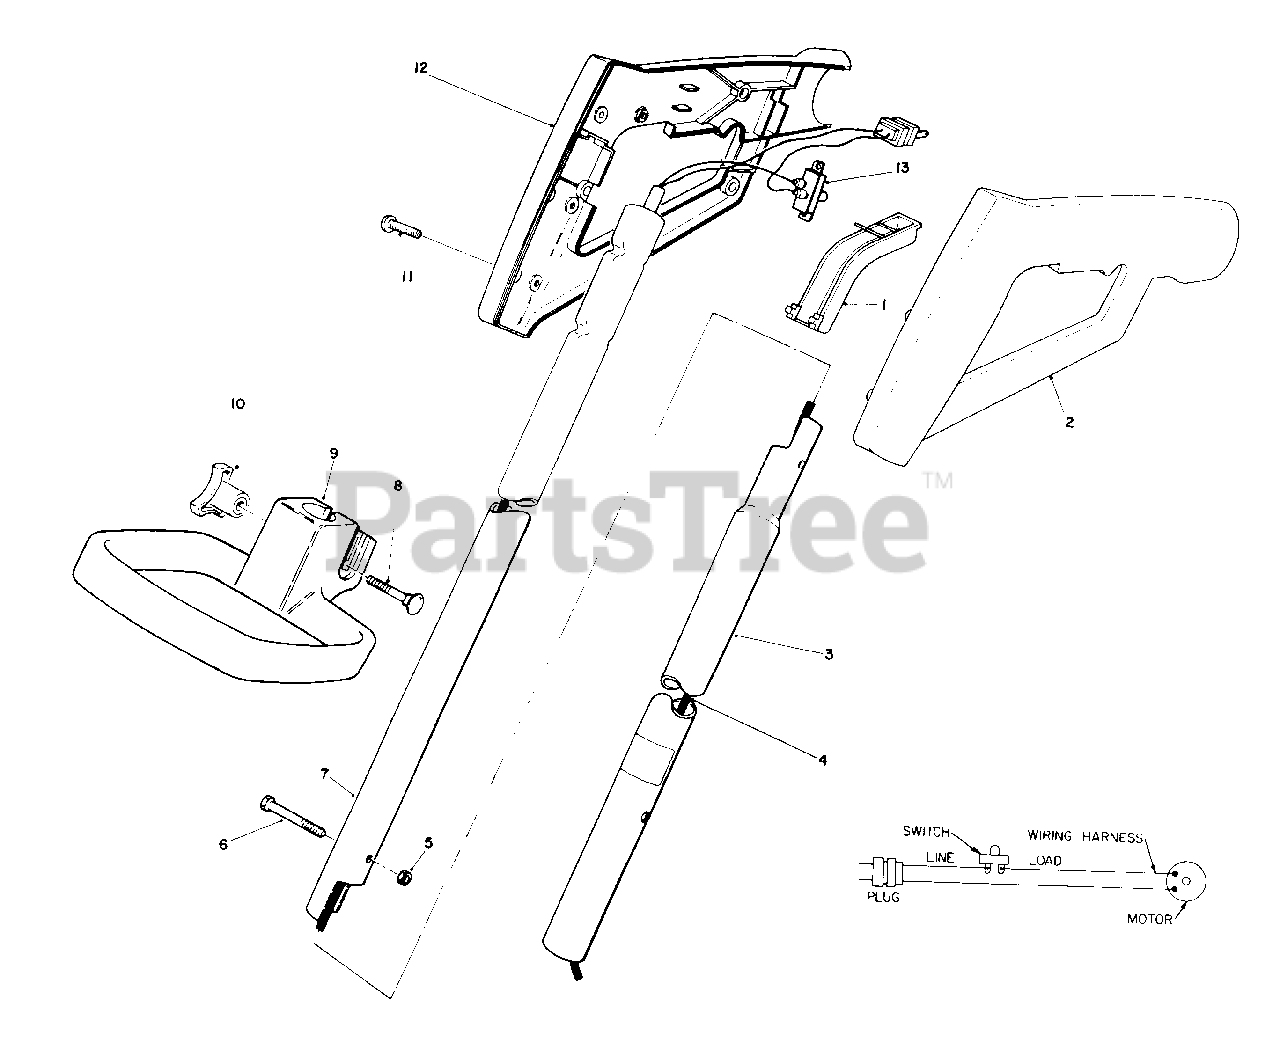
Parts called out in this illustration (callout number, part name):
1	Bar-Switch
2	Grip-Left Hand
3	Tube-Lower Extension
4	Harness-Wire
5	Nut-Lock
6	Screw-Hex Hd. Machine
7	Tube-Upper Extension
8	Bolt-Carriage
9	Handle-Adjustment
10	Knob-Adjustment
11	Screw-Thread Forming
12	Grip-Right Hand
13	Switch-Single Speed
